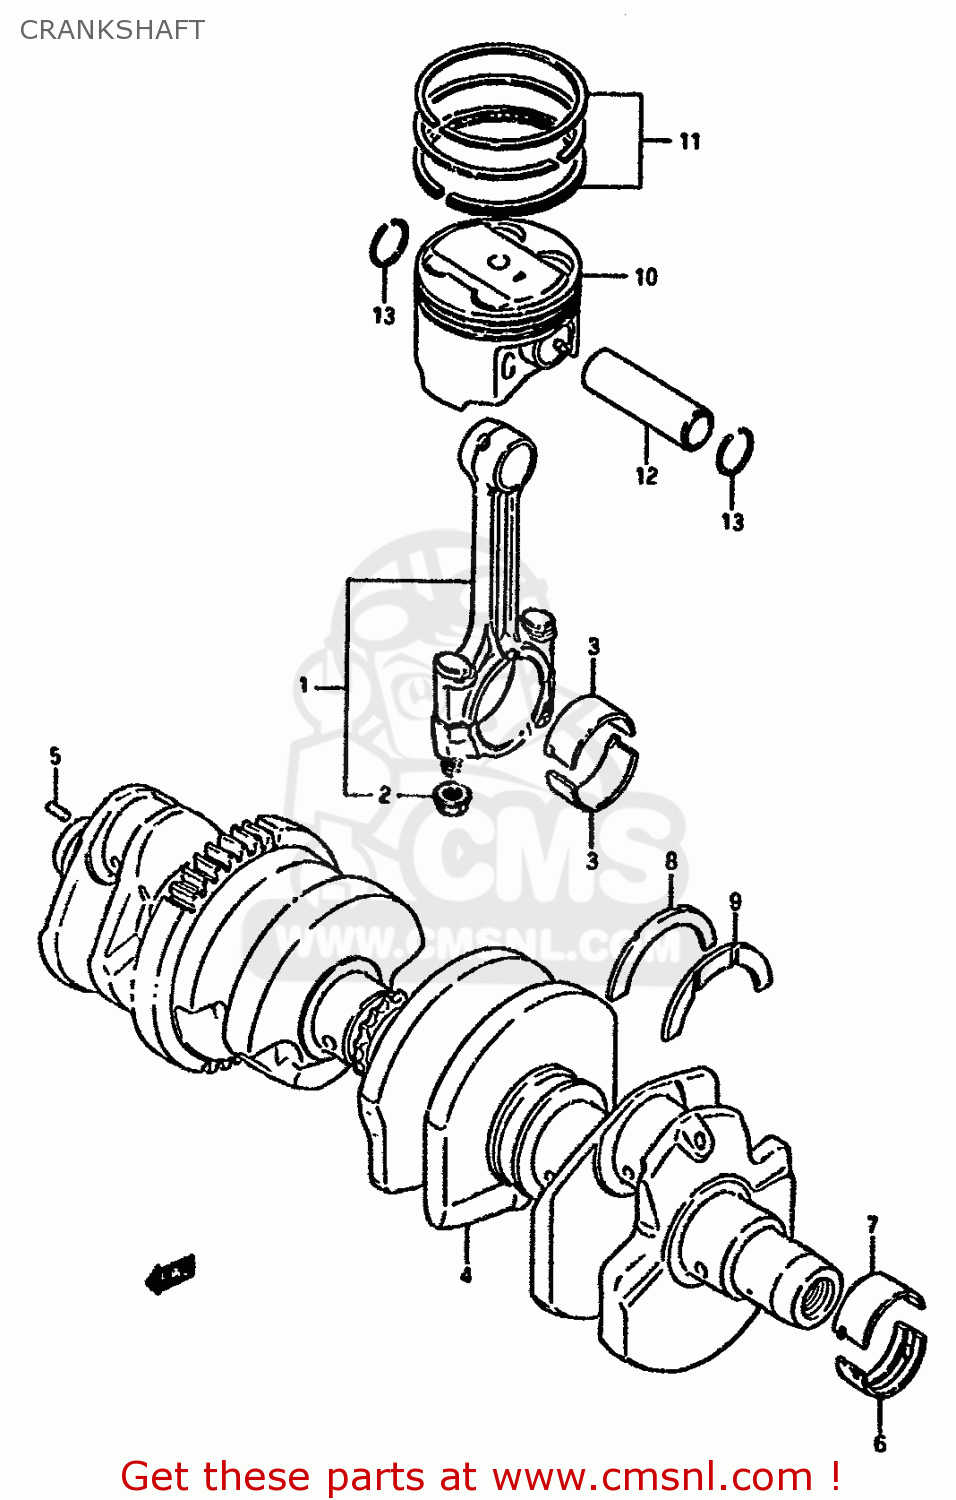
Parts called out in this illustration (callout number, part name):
1	ROD ASSY,CONNECTING
2	NUT
3	BEARING,CRANK PIN
4	CRANKSHAFT
5	PIN
6	BEARING,CRANKSHAFT LWR
7	BEARING,CRANKSHAFT UPR
8	BEARING,CRANK THRUST(GREEN)
9	BEARING,CRANK THRUST(RED)
10	PISTON
11	RING SET,PISTON
12	PIN,PISTON
13	CIRCLIP,PISTON PIN
